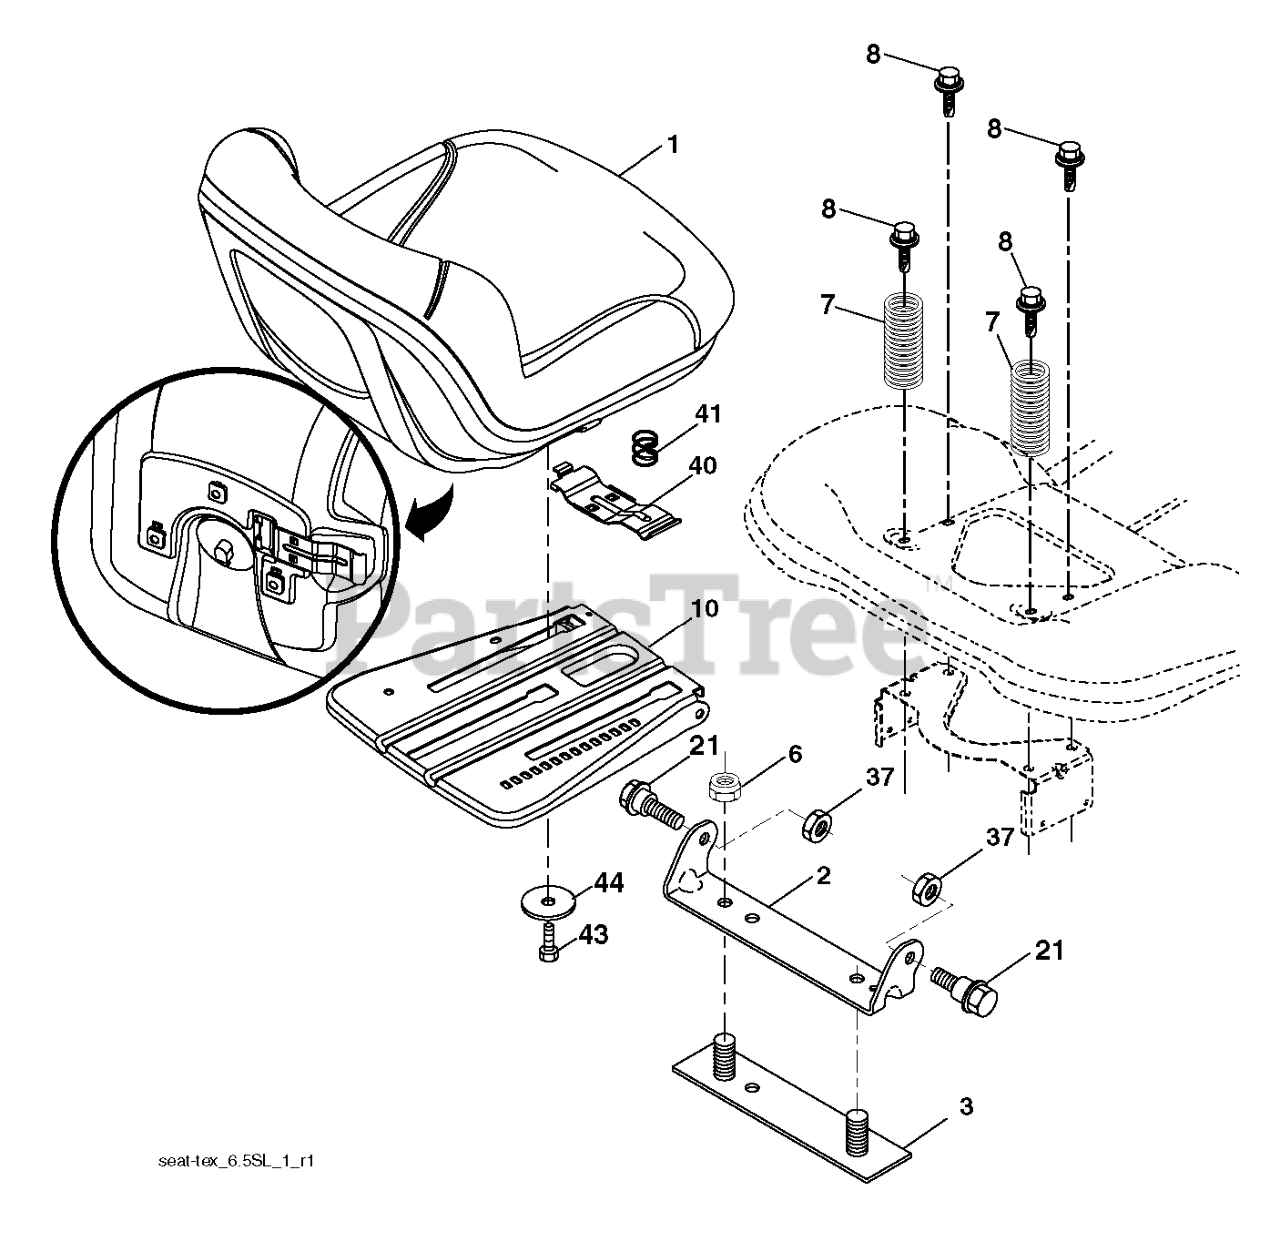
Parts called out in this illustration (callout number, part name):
1	RP SEAT.TH130.GRY.MILSCO.
2	BRKT.PIVOT.FENDER
3	STRAP
6	NUT
7	SPRING COMPRESSION
8	BOLT.5/16-18UNCX3/4 W/SEMS.BLK
10	PAN.ASM.SEAT.3PT
21	BOLT.SHOULDER.5/16-18
37	NUT.71038.31-18.HEX.NYLOCK
40	HANDLE.SLIDE.SEAT.TEX.BLACK
41	SPRING.LATCH.SEAT.TEX
44	WASHER 13/32 X 2-3/8 X 12GA
